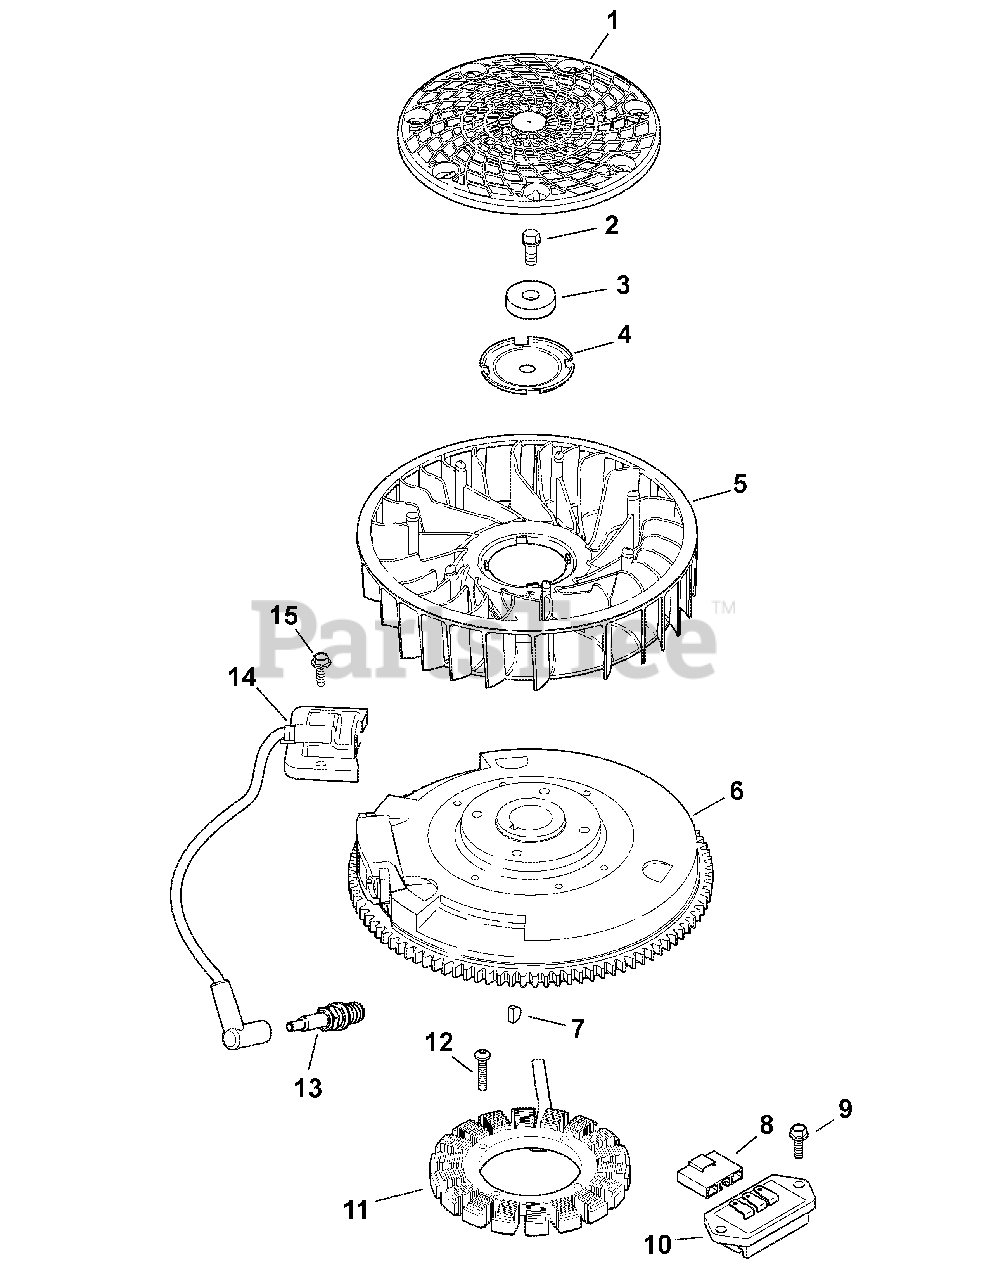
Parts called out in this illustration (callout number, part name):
1	Screen, Grass
2	Screw, Flange, M10 x 1.5 x 45
3	Washer, Flat 13/32
4	Plate, Fan Mounting
5	Fan
6	Flywheel
7	Key, 3/16 x 5/8
9	Screw, Flange, M5 x 0.8 x 16
10	Rectifi er-Regulator
11	Kit, 15 Amp Stator
12	Screw, Torx Head Drive
13	Plug, Spark
14	Module, Ignition
15	Screw, Flnge Thrd. Frmng M5 x 0.8x 20
